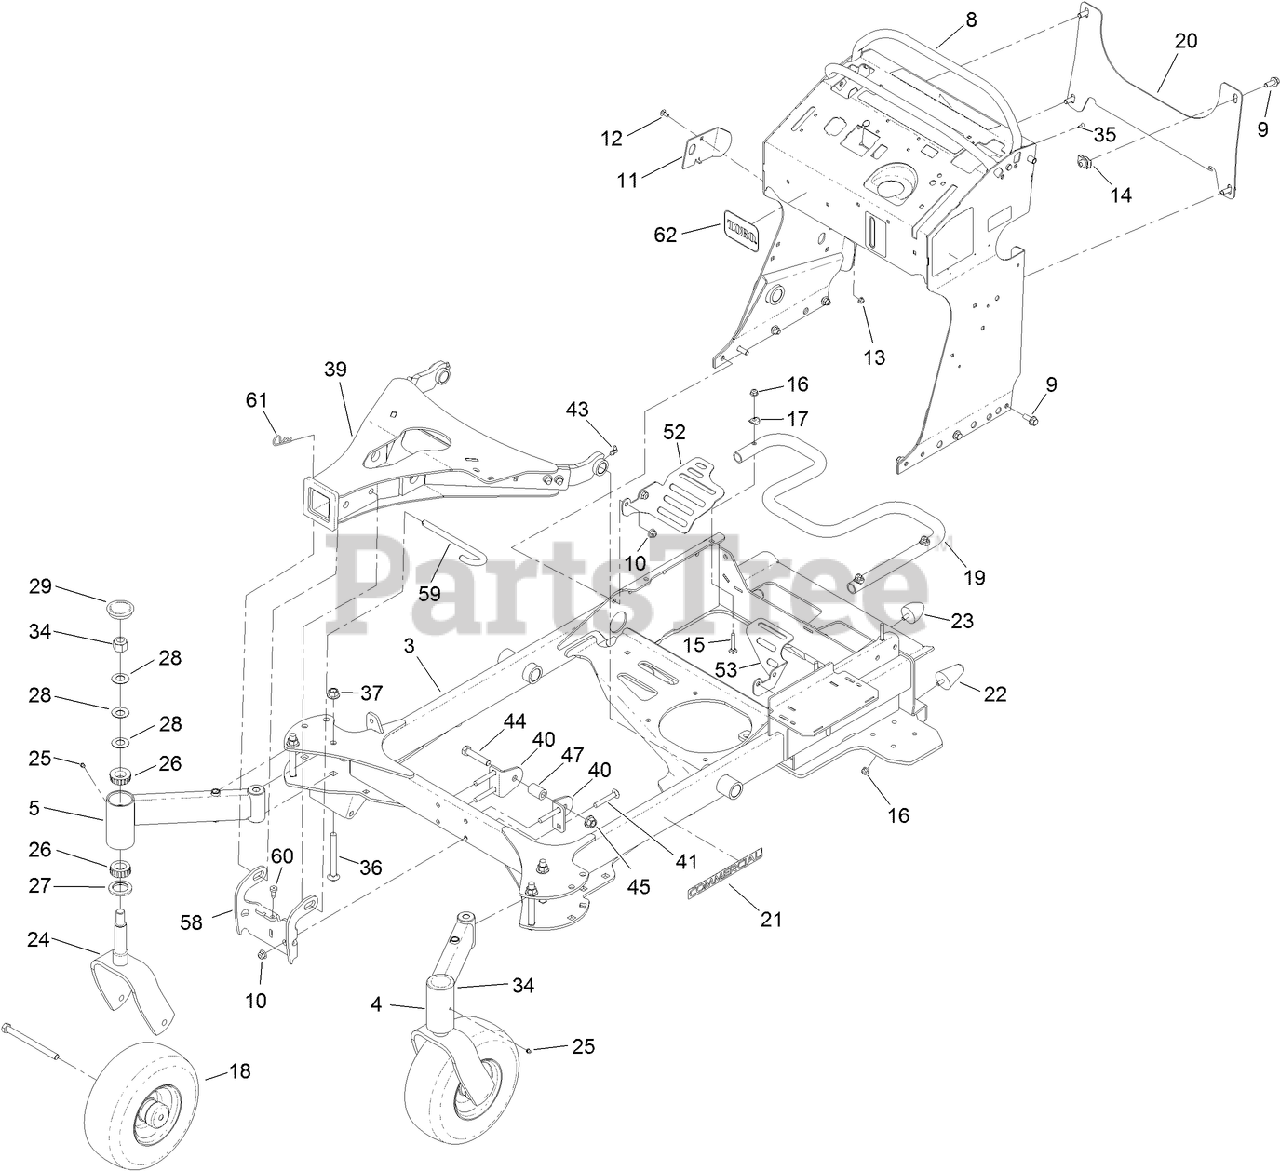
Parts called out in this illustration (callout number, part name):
4	TUBE-CASTOR, SHORT
5	TUBE-CASTOR, LONG
8	TOWER DECAL ASM
9	SCREW-HHF
10	NUT-HF, NI
11	PLATE-STRIKER
12	SCREW-CARR
13	NUT-HF
14	Nut-Tinnerman
15	SCREW-CARR
16	NUT-HF, NI
17	WASHER
18	WHEEL/TIRE AND BEARING ASM
19	TUBE-MOUNT, FUEL TANK
20	BRACKET-CROSS
21	DECAL-COMMERCIAL
22	BUMPER-RUBBER
23	BUMPER-RUBBER
24	FORK-CASTER
26	BEARING-ROLLER, TAPERED
27	SEAL-GREASE
28	WASHER-BELLVILLE
29	CAP-GREASE
34	NUT-LOCK, NI
35	RIVET-POP
36	SCREW-CARR
37	NUT-LOCK
39	A-FRAME ASM
40	BRACKET-CYLINDER
41	SCREW-CARR
43	FITTING-GREASE, 90 DEG
44	SCREW-HH
45	NUT-LOCK
47	SPACER
52	GUARD-FAN, RH
53	GUARD-FAN, LH
58	BRACKET-LOCK
59	PIN-HITCH
60	BUMPER-RUBBER
61	PIN-HAIR
62	DECAL-LOGO, TORO
